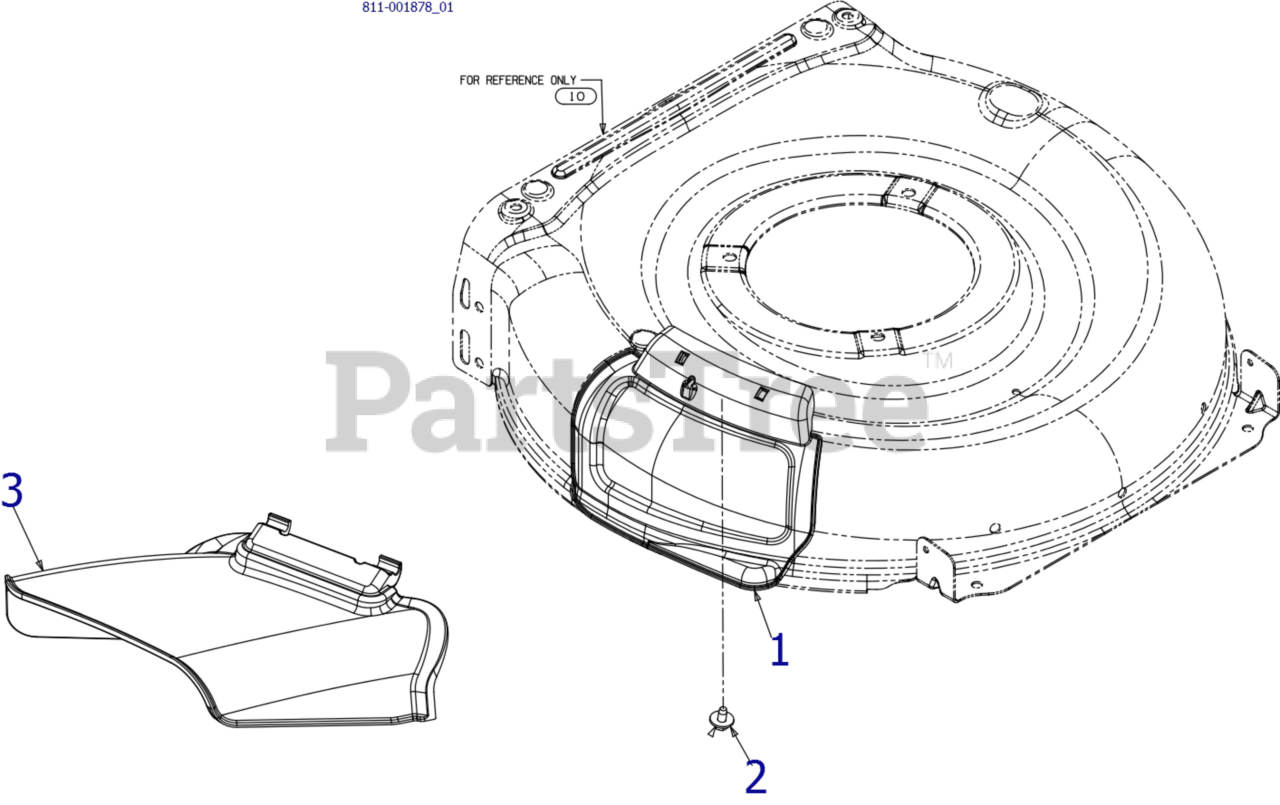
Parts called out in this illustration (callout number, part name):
1	MULCH PLUG ASSEMBLY
2	SCREW 1/4-20 x .50
3	SIDE DISCHARGE CHUTE
